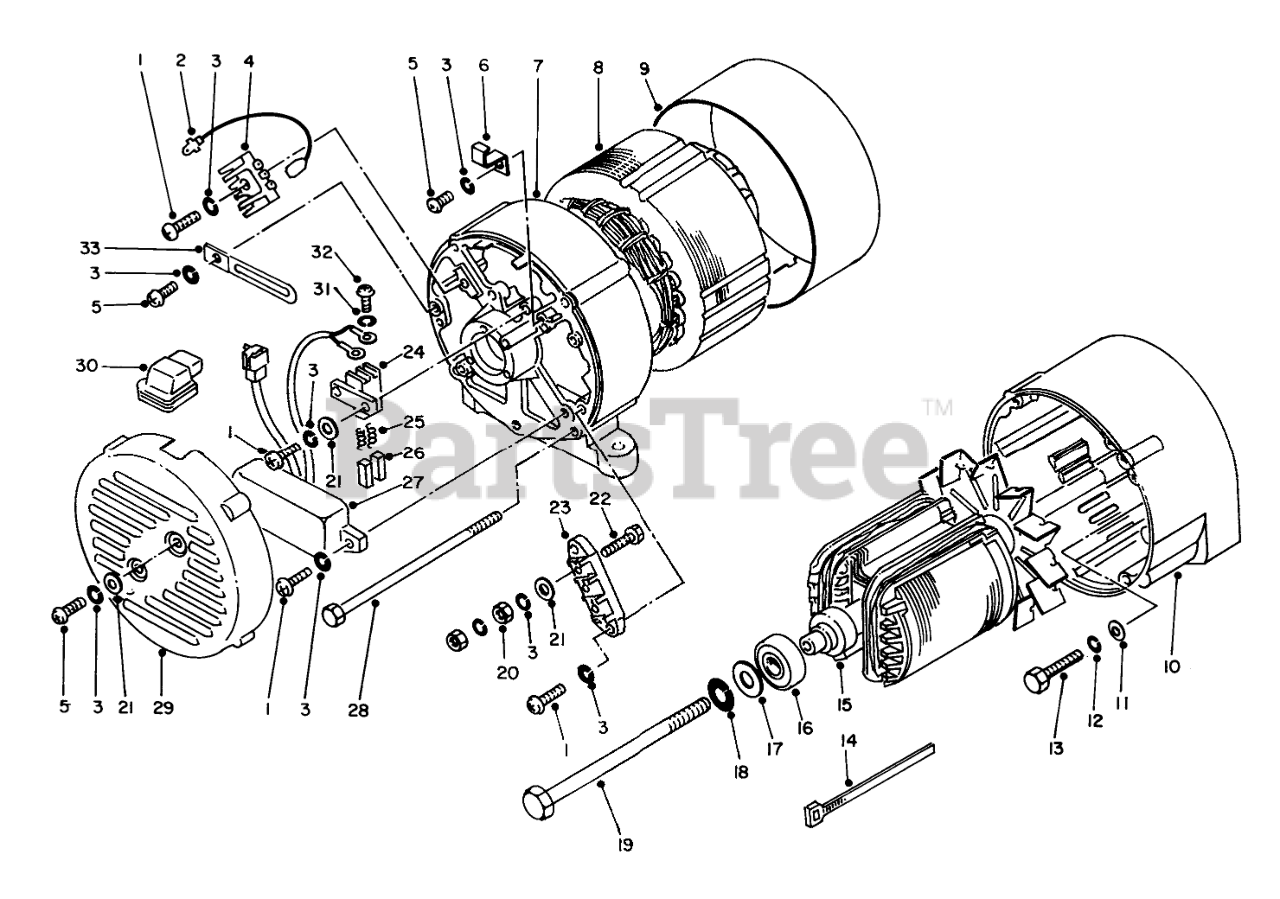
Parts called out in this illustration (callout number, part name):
1	Screw
2	Fusible Link
3	Washer
4	Rectifier
5	SCREW
6	Clamp
7	Housing-Rear
8	Stator (120V +120V/240V)
9	Cover-Stator Core
10	Housing-Front
11	Washer
12	WASHER-LOCK
14	Clamp
15	Rotor
16	Bearing
17	WASHER
18	Washer-Lock
19	Bolt-Rotor
21	WASHER
23	Terminal Assembly (Incl. Ref. #3 & 20-22)
24	Brush Assembly (Incl. Ref. #25, 26 & 31-32)
25	Spring
26	BRUSH
27	REGULATOR
28	Bolt-Stator
29	Cover-Rear
30	Grommet
31	Lockwasher
33	Clamp
